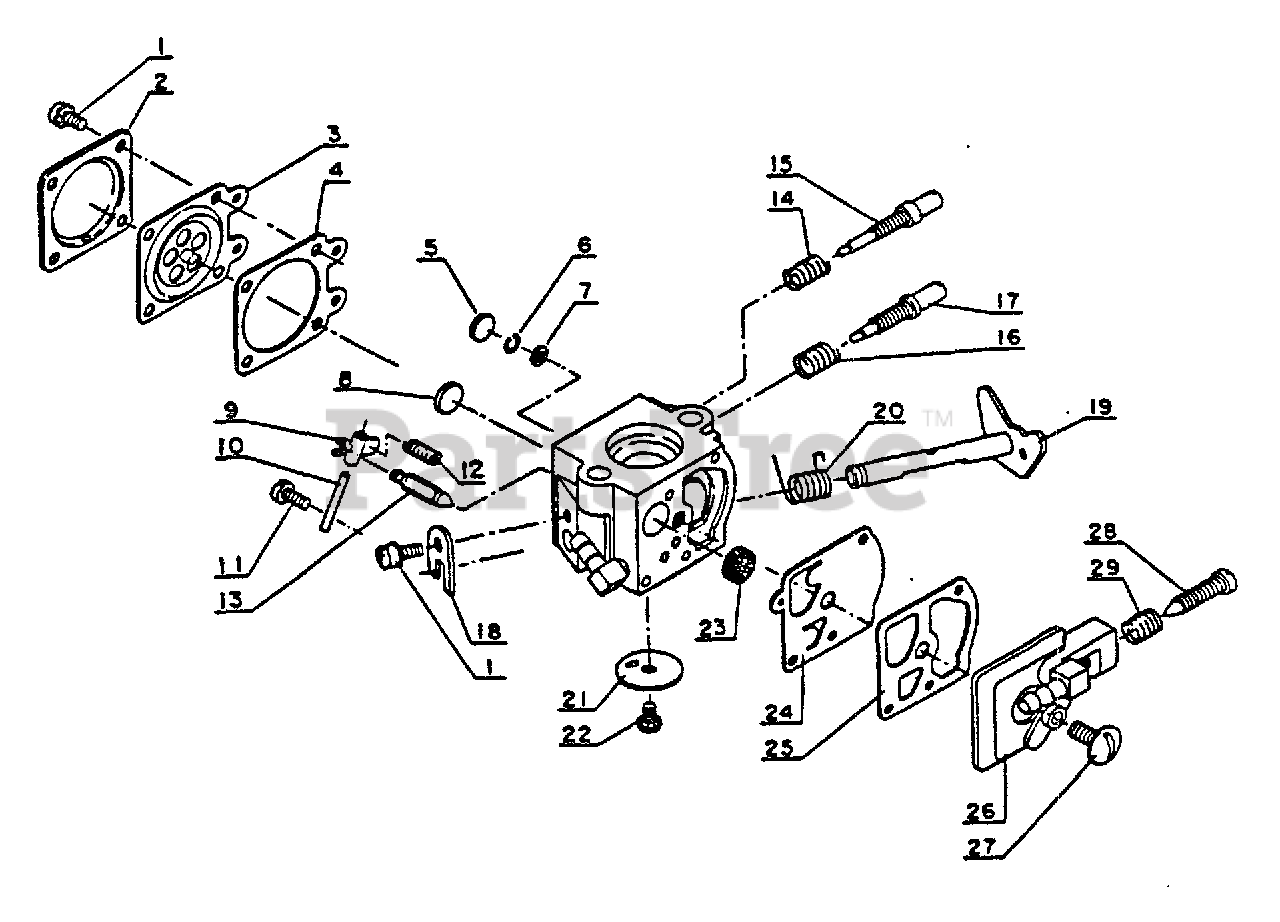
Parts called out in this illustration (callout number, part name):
1	SCREW
2	COVER, METERING
3	DIAPHRAGM, METERING
4	GASKET, METERING
5	PLUG, WELCH
6	RING, SCREEN RETAINING
7	STRAINER
8	PLUG, WELCH
9	LEVER, METERING
10	PIN, METERING LEVER
11	SCREW
12	SPRING, METERING LEVER
13	VALVE, INLET NEEDLE
14	SPRING, NEEDLE ADJUST
15	NEEDLE - HIGH SPEED
16	SPRING, NEEDLE ADJUST
17	NEEDLE - LOW SPEED
18	CLIP, THROTTLE SHAFT
19	SHAFT, THROTTLE
20	SPRING, THROTTLE RETURN
21	VALVE, THROTTLE
23	STRAINER
24	DIAPHRAGM, PURGE
25	GASKET, PURGE
26	COVER, PUMP
27	SCREW, PUMP COVER
28	SCREW, IDLE ADJUST
29	SPRING, IDLE ADJUST
